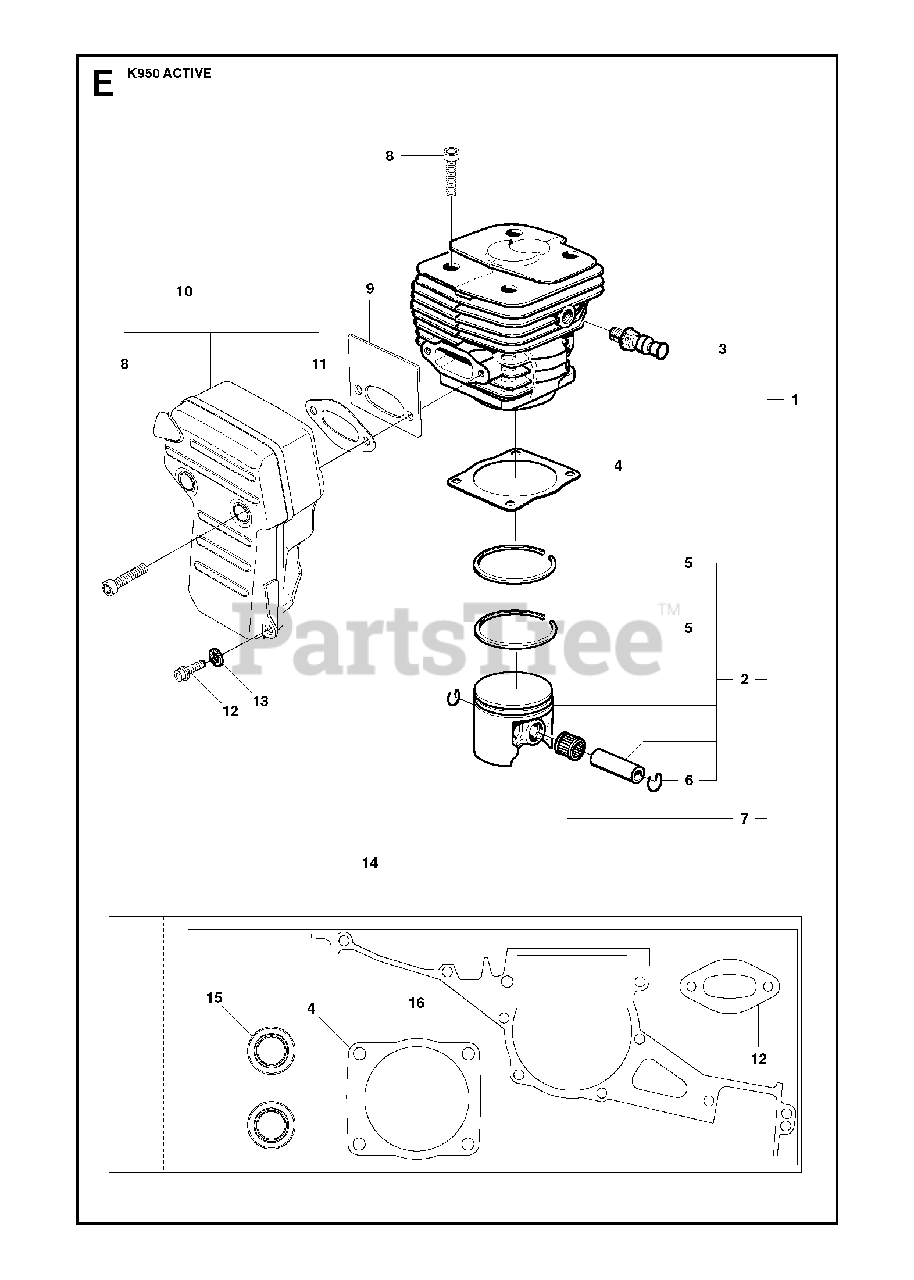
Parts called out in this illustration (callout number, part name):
1	CYLINDER ASSYIncl. 2, 7
2	PISTON ASSYIncl. 5, 6
3	DECOMPRESSION VALVE
4	CYLINDER BASE GASKETGasket kit 14
7	NEEDLE BEARING
9	COOLING PLATE
10	MUFFLER ASSYIncl. 8, 12
11	GASKETGasket kit 14
12	SCREW IHSCFM
15	SEALING RING
